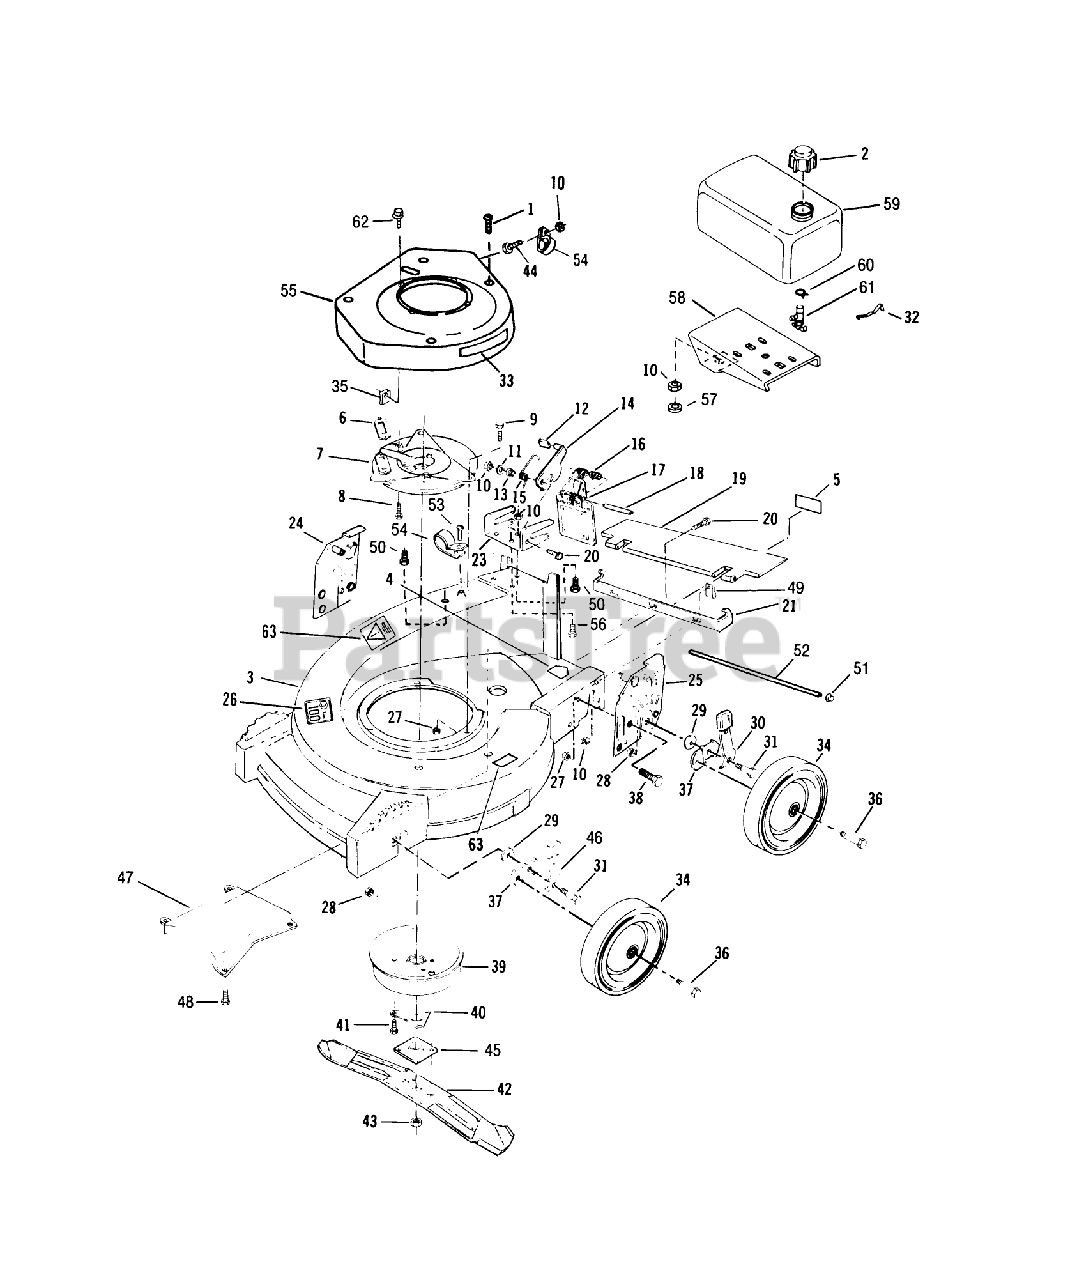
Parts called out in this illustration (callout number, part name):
1	SCREW - SELF TAPPING
2	FUEL CAP & INSERT
7	PLATE F
8	SCREW V
9	SCREW-HH
10	LOCKNUT E
12	KNOB (S&R)
15	SPRING
16	SPRING ASOC
18	ROD (RB&W)
19	T/SHIELD SM&P
27	NUT-LOCK F
28	LOCKNUT
29	WASHER
31	BOLT
32	SPRING
35	PUSHNUT F
36	BOLT-SHOULDER
39	MUFFLER COVER F
40	SUPPORT F
41	SCREW
43	NUT-BLADE
45	PLATE AND COLLAR ASM
46	SPRING ARM ASM
47	BAFFLE CHUTE PL
50	SCREW HEX WASHER
53	SCREW LAWRENCE
56	SCREW
57	WASHER
58	BRACKET - TANK
60	CLAMP - HOSE S
61	VALVE&SCREEN SM
62	SCREW SEMS SM
